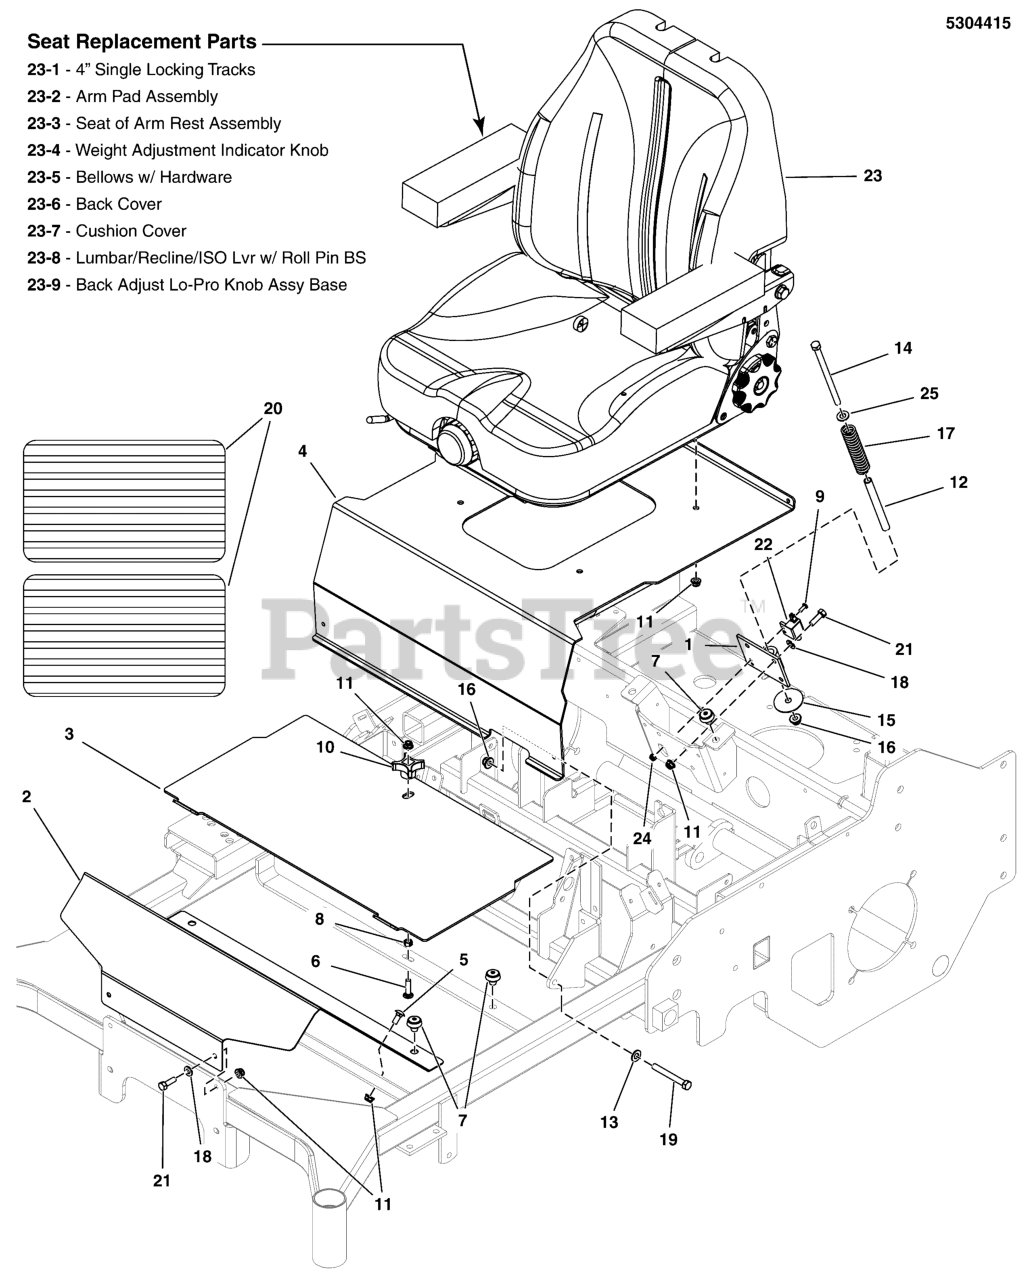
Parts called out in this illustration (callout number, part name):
1	WELD, SEAT SWITCH
2	PLATE, RIGID FLOOR, S320Z - RED
3	PLATE, REMOVABLE FLOOR, 200XT - RED
4	ASSM, SEAT PLATE W/ DECAL, F320Z-DOM
5	BOLT, 5/16-18 X 3/4, CARRIAGE, GD5, CZ
6	BOLT,5/16-18X1.500,CARRIAGE,SQ,GR5,ZC/CL
7	MNT, VBRTN, RBBR
8	NUT, 5/16-1/8, HEX, CNTR LK, ZINC PHOS/OIL
9	SCREW, #10-24 X 3/4" ROUND PHILLIPS
10	KNOB-INT THR .312-18 4-ARM 2.12WD 1.06LG
11	NUT, 5/16-18 HEX NYLOCK FLANGE NUT
12	SPACER, .38 X .50 X 5.06, CZ
13	WASHER, 3/8 SAE
14	BOLT, 3/8-16 X 6" GD5 CZ
15	WASHER, .39 X 2.00 X X .14
16	NUT, 3/8 - 16 HEX NYLOCK FLANGE
17	SPRING, .688 ID X .130 WIRE DIA 4.25
18	WASHER, 5/16" SAE
19	BOLT, 3/8-16 X 3" GD5 CZ
20	SAFETY WALK, 10.00 X 19.00
21	BOLT, 5/16-18 X 1" GRD5 YZ
22	SWITCH, PLUNGER, N.C.
23	SEAT, HIGH BACK WITH SUSPENSION
23-1	4" SINGLE LOCKING TRACKS BASE
23-2	ARM PAD ASSEMBLY BLK/CHAR CAR FIB/HARBR GRY RED WELT
23-3	SET OF ARMREST ASSEMBLY BLK/CHAR CAR FIB/HARBR GRY RED WELT
23-4	WEIGHT ADJUST INDICATOR KNOB ASSY BASE
23-5	BELLOWS W/ HARDWARE BASE
23-6	BACK COVER FOR FIXED BACK I3M BLK/CHAR CAR FIB/HARBR GRY RED WELT
23-7	CUSHION COVER FOR I3M BLK/CHAR CAR FIB/HARBR GRY RED WELT
23-8	LUMBAR/RECLINE/ISO LVR W/ RLL PIN BS
23-9	BACK ADJST LO-PRO KNOB-HRDWR BASE
24	NUT, Hex, Nylon Lock, #10-24
25	WASHER, 3/8" USS
